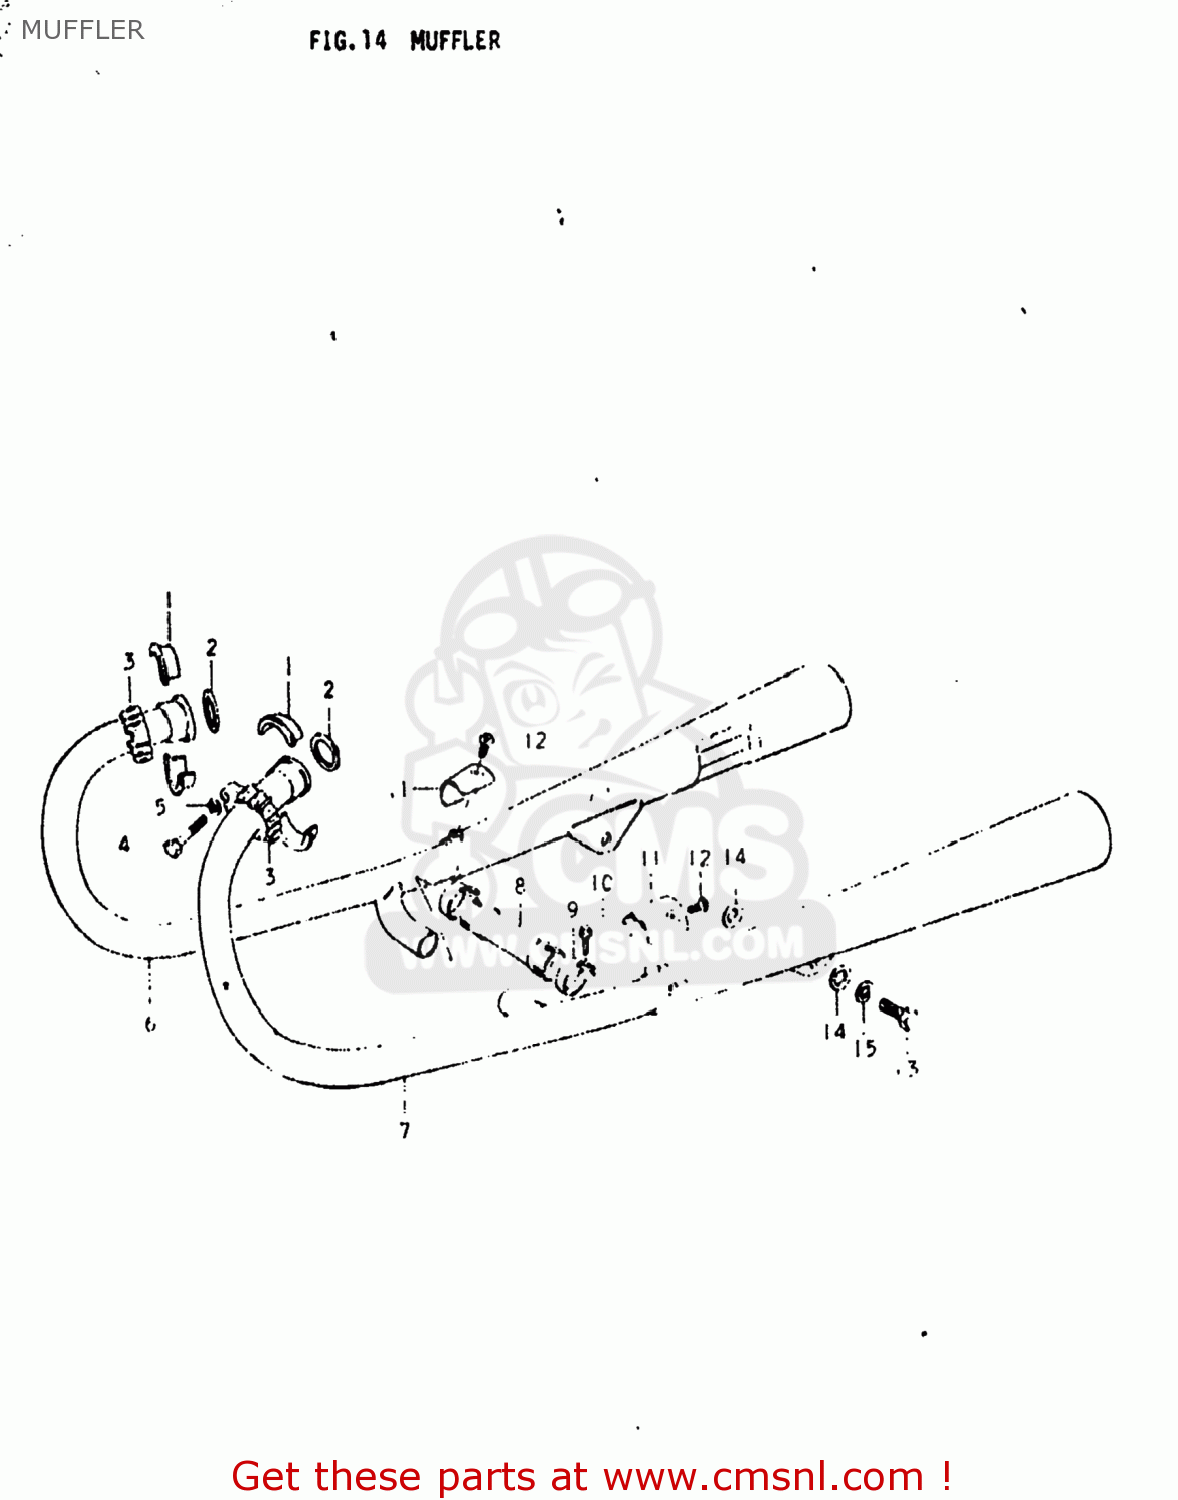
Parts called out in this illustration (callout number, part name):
1	PLATE,EXHAUST
2	GASKET,EXHAUST PIPE (NAS)
3	CLAMP,EXHAUST PIPE
4	BOLT
5	LOCK WASHER
6	BODY,MUFFLER
7	BODY,MUFFLER
8	PIPE,EXHAUST COUPLER
9	CLAMP
10	BOLT,REAR
11	COVER,MUFFLER,RIGHT
12	SCREW
13	BOLT 10X25
14	WASHER
15	LOCK WASHER
